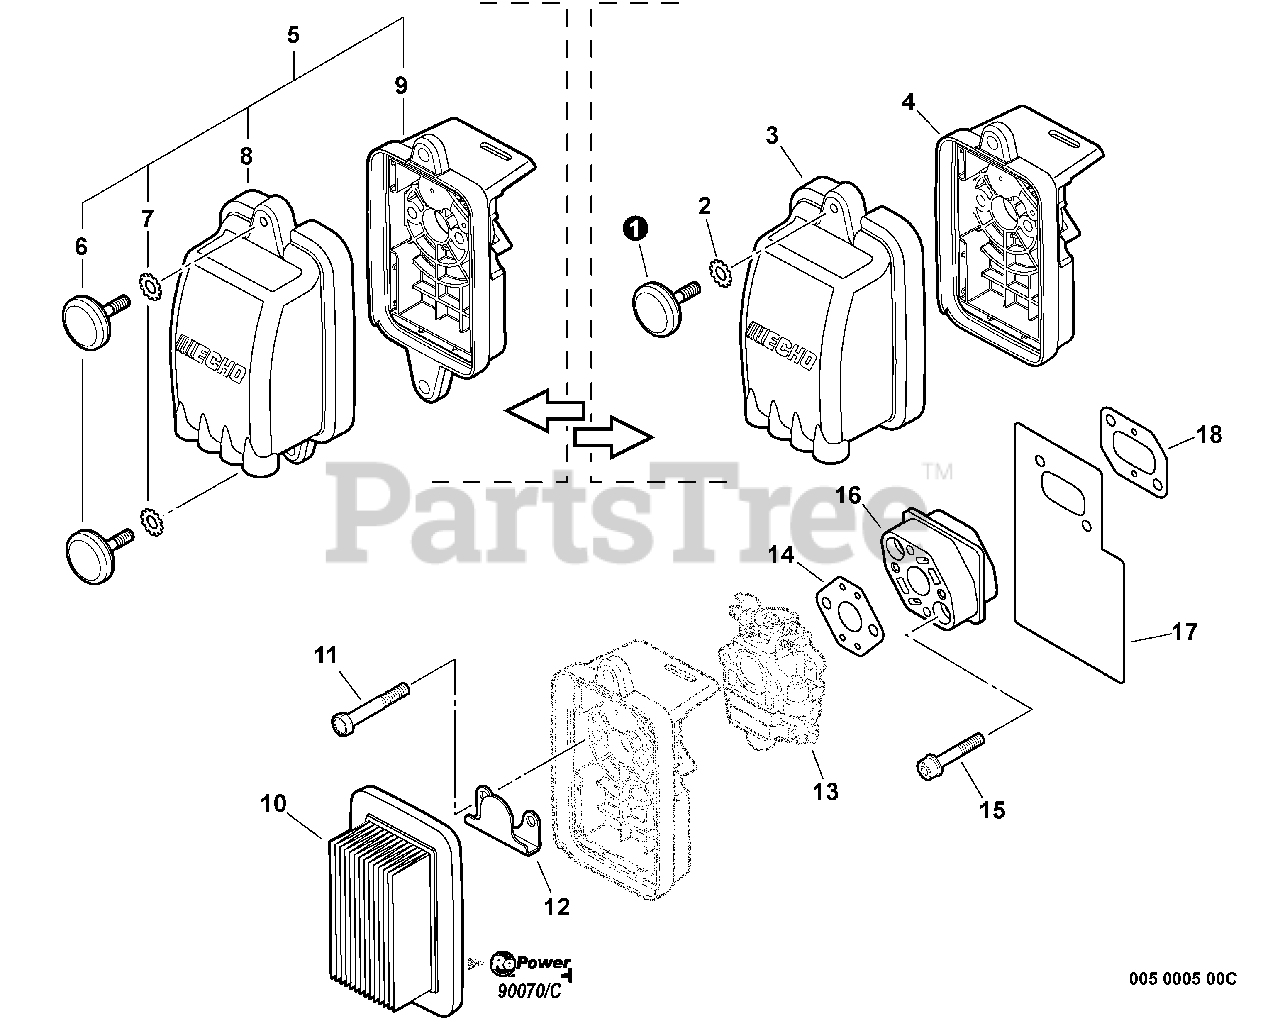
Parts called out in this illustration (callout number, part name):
1	THUMBSCREW
3	COVER, AIR FILTER
4	AIR FILTER CASE ASSY
5	FILTER KIT, AIR
6	THUMBSCREW
8	COVER, AIR FILTER
9	CASE ASSY, AIR FILTER
10	FILTER, AIR
11	BOLT 5×55
12	PLATE, PREVENT
13	CARBURETOR
14	GASKET, INTAKE
15	BOLT 5×25
16	INSULATOR, INTAKE
17	HEAT SHIELD, INTAKE
18	GASKET, INTAKE
19	TUNE-UP KIT - REPOWER
